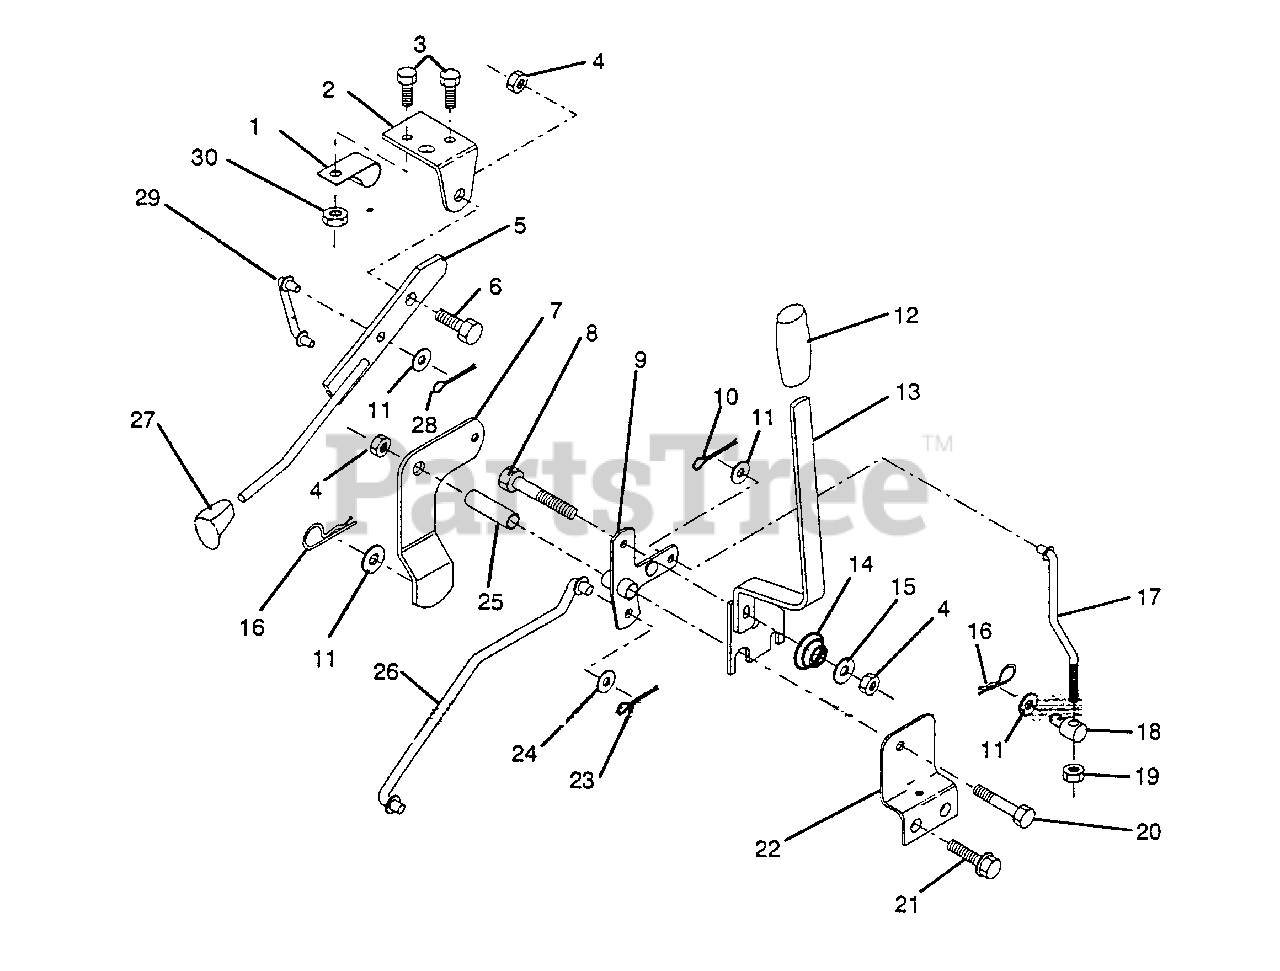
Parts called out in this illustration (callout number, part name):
1	Clip, Insulated
2	Bracket, Mower Clutch
3	Bolt, Fin. Hex 1/4-20 Unc x 1/2 Gr. 5
4	Nut, Crownlock 3/8-16 UNC
5	Assembly, Clutch Lever
6	Bolt, Shoulder
7	Assembly, Mower Clutch Arm
8	Bolt, Hex 3/8-16 UNC x 2-1/4
9	Assembly, Bellcrank Lift
10	Pin, Cotter 1/8 x 3/4
11	Washer, 13/32 x 13/16 x 16 Ga.
12	Grip, Handle
13	Assembly, Lift Handle
14	Spring, Compression
15	Washer, 13/32 x 3/4 x 12 Ga.
16	Retainer, Spring
17	Link, Front Lift
18	Trunnion, Threaded 3/8-16
19	Nut, Hex Jam 3/8 x 16 UNC
20	Bolt, Fin. Hex 3/8-16 UNC x 2-3/4
21	Screw, Hex Thdrol. 5/16-18 x 1/2
22	Bracket, Mower Height
23	Pin, Cotter 1/8 x 1
24	Washer 17/32 x 1 x 16 Ga.
25	Tube, Spacer
26	Rod, Mower Lift
28	Pin, Cotter 3/32 x 3/4
29	Link, Mower Clutch
30	Nut, Crownlock 1/4-20
